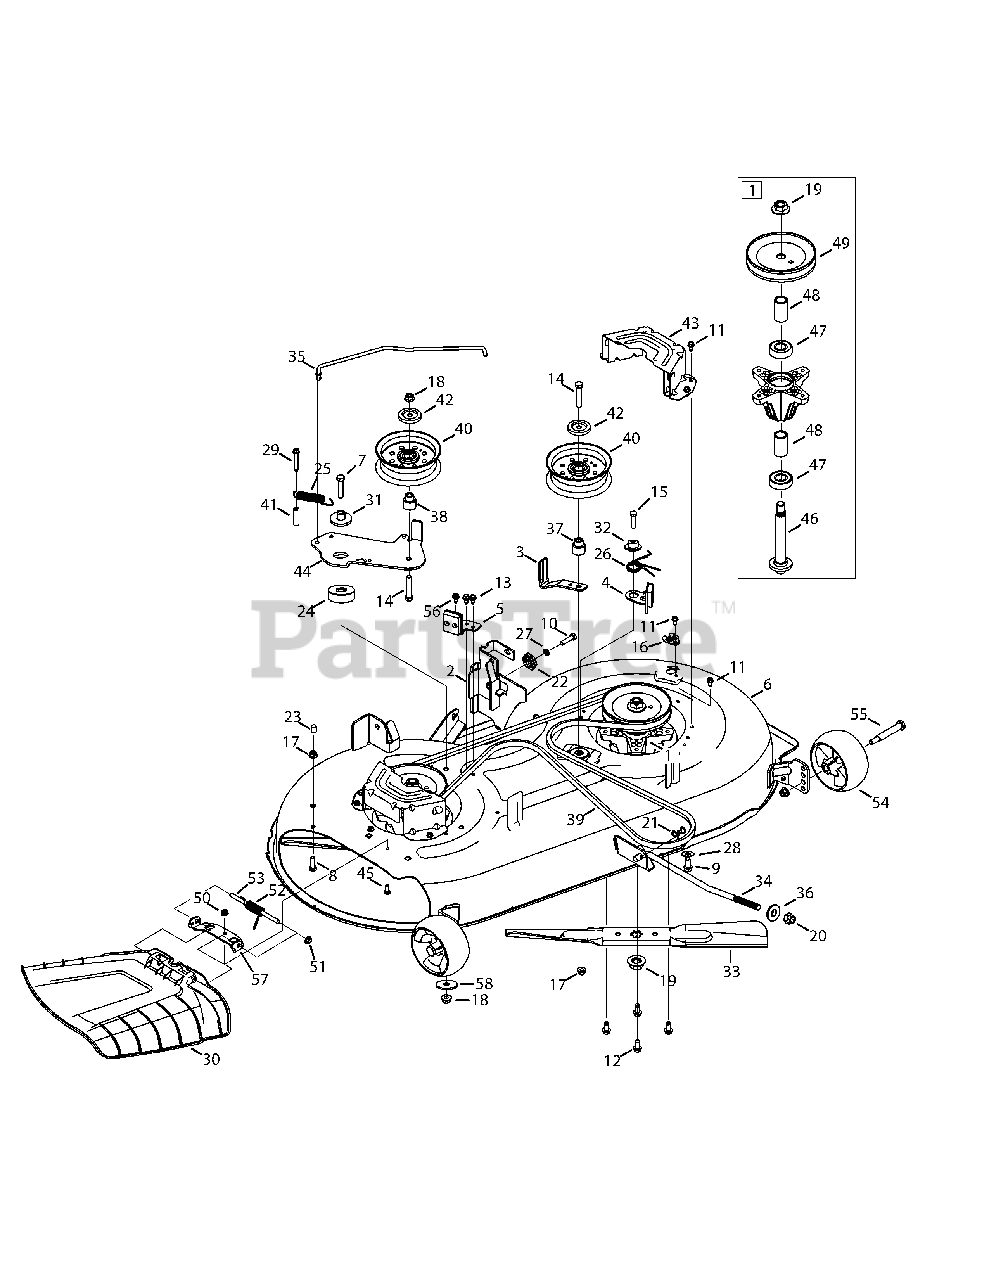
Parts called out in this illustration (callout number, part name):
1	Spindle Ass’y, Pulley, 6.2 Dia
2	Bracket Ass’y, Deck, Hanger LH
3	Belt Keeper
4	Brake Assembly, Deck, LH
5	Brake Assembly, Deck, RH
6	Deck, 42"
7	Hex Screw, 3/8-16 x 1.75
8	Hex Cap Screw, 5/16-18 x 1.00
9	Screw, Self-tapping, 5/16-18, .750
10	Hex Screw, 5/16-18, 1.25, Gr5, Std
11	Screw, Self-tapping, 1/4-20, 0.500
12	Screw, 5/16-18 x 0.750
13	Screw, M6-1 x .625
14	Hex Screw, 3/8-16, 2.00, Gr8, Std
15	Hex cap Screw, 5/16-18 x 1.25
16	Deck Wash Plug
17	Nut, Flange Lock, 5/16-18, Grf
18	Nut, Flange Lock, 3/8-16, Grf
19	Nut, Flange, 5/8-18
20	Flange Lock Nut, 1/2-13
21	Bow-Tie Cotter Pin
22	Gear, Deck, Adjustment
23	Cap, .290 x .500
24	Spacer, .385 x 1.75 x .585
25	Extension Spring, .750 X 4.77
26	Torsion Spring, LH
27	Washer, Lock, 5/16, Regular Duty
28	Flat Washer, .406 x .875 x .059
29	Screw, Self Tapping, 1/4-20, 1.50
30	Chute Deflector Assembly
31	Shoulder Spacer, .970 x .190
32	Shoulder Spacer, .75 x .145
33	Blade, Cut, 21.23" 2-In-1
34	Rod, Lift, Deck, Frt, 12.7
36	Deck Lift Pivot Cup
37	Shoulder Spacer, Idler
38	Shoulder Spacer, Pivot Idler
39	Belt, V Type, A Sec X 96.5
40	Pulley, Idler, 4.50"Dia
41	Spacer, .260 x .375 x 1.030
42	Pulley Cap
43	Deck Belt Cover, 42
44	Deck Idler Bracket
45	Hex Cap Screw, 1/4-20 x .62
46	Shift, Spindle, 6.11.
47	Bearing, Ball, .787id x 1.85 Odx.551
48	Spacer, .792 x 1.060 x 1.860
49	Pulley, Deck, 5.4 Dia
50	Nut, Flange Lock, 1/4-20, Nylon
51	Push Cap
52	Spring, Torsion, .440 ID x 1.75
54	Wheel, Deck, 5.0 Dia Ball
55	Bolt, Shoulder, .496 x 2.50, 3/8-16
56	Shoulder Screw, 1/4-20
58	Flat Washer, .406 x 1.50 x .105
